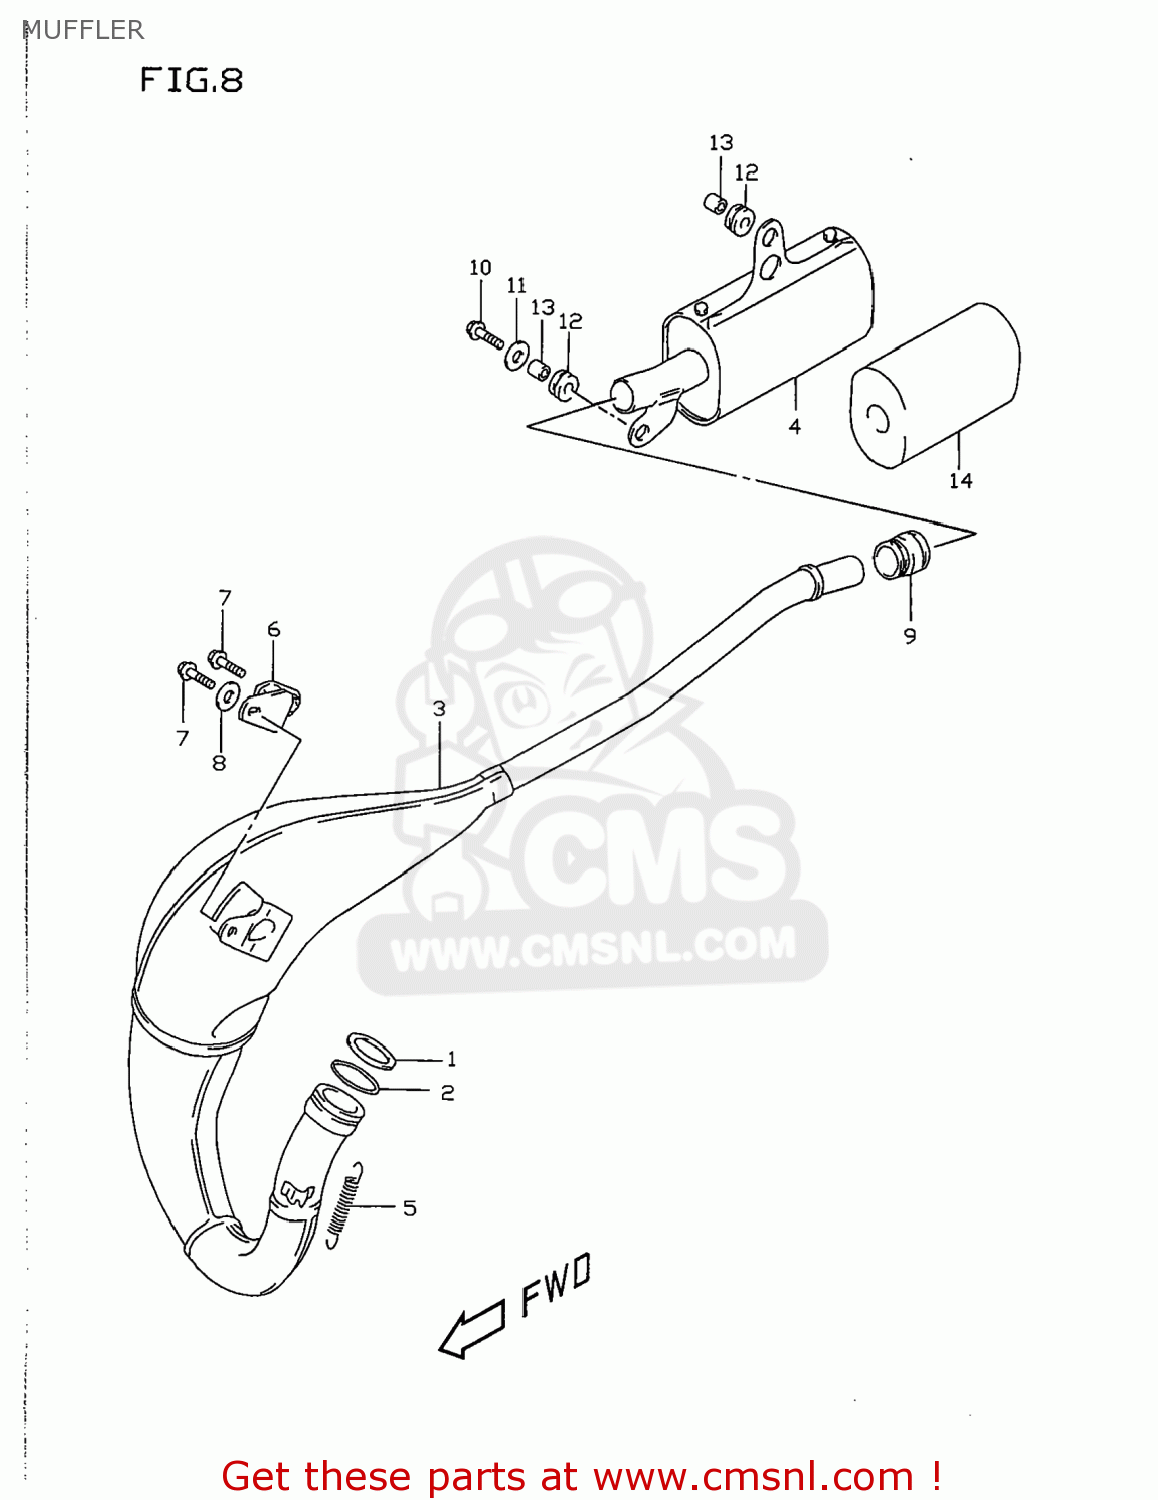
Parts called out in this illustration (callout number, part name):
1	WASHER,EXH FLANGE
2	O RING,EXH FLANGE
3	BODY,MUFFLER 1ST
4	BODY,MUFFLER,SECOND
5	SPRING
6	DAMPER,MUFFLER SUPPORT
7	BOLT
8	WASHER(6.5X16X1.2)
9	CONNECTOR,MUFFLER
10	SCREW
11	WASHER(6.5X20X1.2)
12	CUSHION
13	SPACER
14	SILENCER,MUFFL
